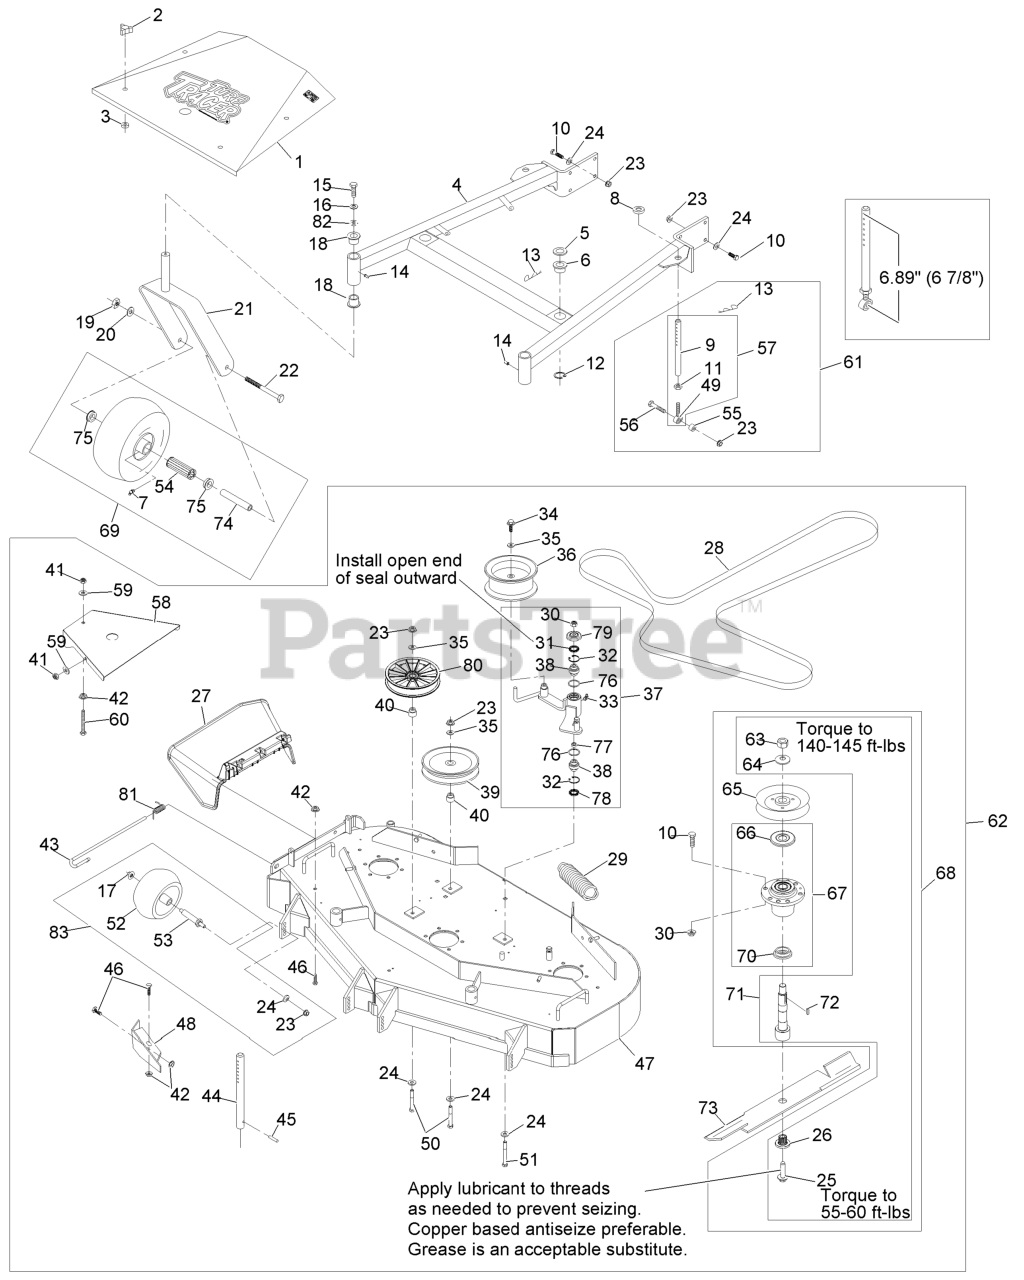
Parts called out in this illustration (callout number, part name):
1	ASM,SHIELD W/DECALS 48 TT
2	KNOB-3 PRONG
4	DECK SUPPORT W/BSHGS 48"
5	SPACER-DECK SUPPORT
6	BUSHING-DECK
7	FITTING-GREASE
9	LINK,SUPPORT
10	SCREW-HH
11	NUT-HJ
12	RING-RETAINING
13	PIN,HAIR COTTER
14	FITTING-GREASE
15	SCREW-HH
16	WASHER-LOCK
17	Nut-Nyloc 3/8-16 Flg
18	BEARING-FLANGED
19	NUT-HH
20	WASHER-LOCK
22	SCREW-HH
23	NUT-HHF, WHIZ
24	WASHER-BELLEVILLE
25	SCREW,SEMS 1/2-20 X 2.19
26	BUSHING,SPLINED
27	CHUTE DEFLECTOR XRK M056
28	BELT - V, B
30	NUT-LOCK, NI
31	SEAL-LIP, SINGLE
32	RING-SNAP
33	FITTING-GREASE, 90 DEG
34	SCREW-HHF
35	WASHER-FLAT
37	KIT, DECK IDLER TTHP48&52
38	BEARING-SPHERICAL
39	PULLEY-IDLER
40	BUSHING-IDLER
41	NUT-LOCK, NI
43	PIN-CHUTE
44	ROD,DECK SUPPORT
46	SCREW-HH
47	ASM,DECK W/DECALS TTHP/MH
48	BAFFLE,DOGLEG
49	BALLJOINT
50	SCREW-HH
51	SCREW-HH
52	ROLLER-SCALP, ANTI
54	BEARING
56	SCREW-HH
58	SHIELD,BELT
59	WASHER-FLAT
60	BOLT,TAP HH
61	KIT,SUPPORT LINK W/PIN
62	Asm, Deck Complete
65	SHEAVE,W/HUB 5.72
66	GUARD-BEARING, TOP
67	KIT, CUTTER HOUSING
68	ASM, CUTTER HSG
69	KIT, SP CASTER WHEEL REPL
70	SPACER-GUARD, BOTTOM
71	KIT, SPLINED SPINDLE 103-
72	KEY-RECTANGLE
75	BUSHING
78	SEAL-LIP, DOUBLE
79	GUARD-TOP
80	PULLEY,IDLER 5"
81	SPRING, TORSION
